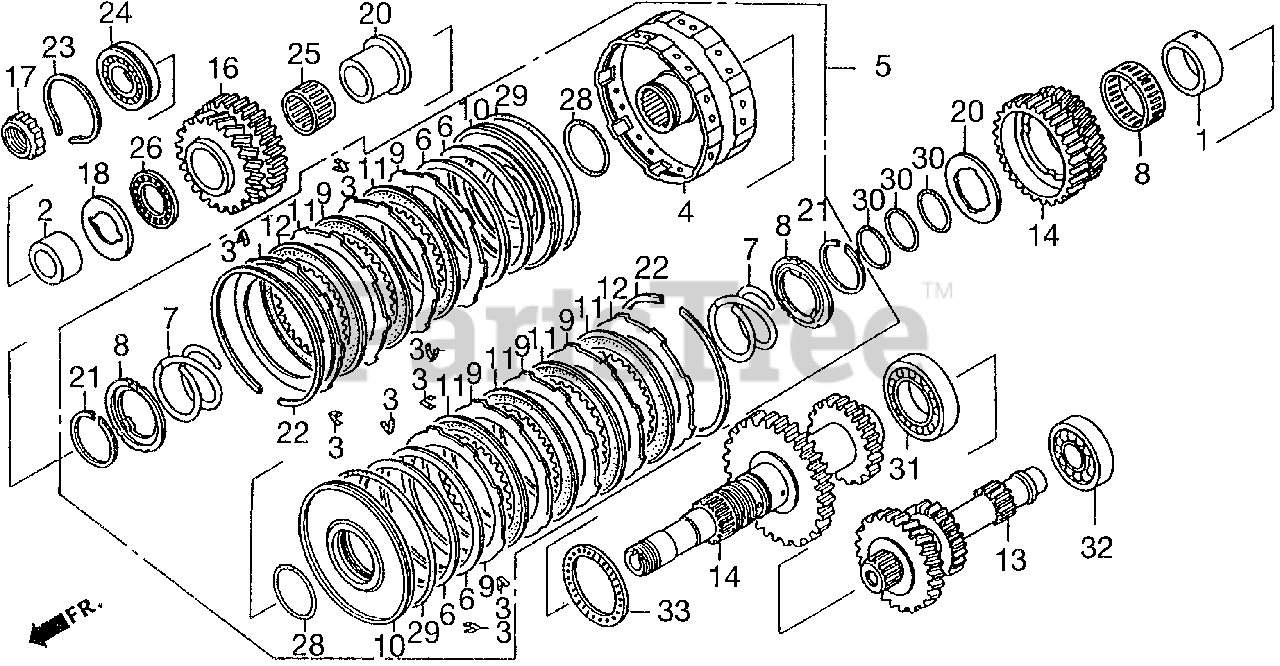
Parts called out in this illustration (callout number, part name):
1	COLLAR, DISTANCE
2	COLLAR (25MM) (NOT AVAILABLE)
3	SPRING, DISK SETTING
4	GUIDE, SECOND & THIRD CLUTCH
5	CLUTCH ASSY., SECOND & THIRD
6	SPRING, CLUTCH DISK
7	SPRING, CLUTCH RETURN
8	SEAT, CLUTCH SPRING
9	PLATE, CLUTCH (106)
10	PISTON, CLUTCH
11	DISK, CLUTCH
12	PLATE, CLUTCH END (2.3MM)
12	PLATE, CLUTCH END (2.6MM)
12	PLATE, CLUTCH END (2.9MM)
12	PLATE, CLUTCH END (3.2MM)
12	PLATE, CLUTCH END (3.5MM)
12	PLATE, CLUTCH END (2.15MM)
12	PLATE, CLUTCH END (2.45MM)
12	PLATE, CLUTCH END (2.75MM)
12	PLATE, CLUTCH END (3.05MM)
12	PLATE, CLUTCH END (3.35MM)
12	PLATE, CLUTCH END (3.65MM)
13	SHAFT, AUXILIARY DRIVE
14	COUNTERSHAFT
15	GEAR, SECOND DRIVEN (38T-28T)
16	GEAR, THIRD DRIVEN (38T-23T)
17	NUT, LOCK (25MM)
18	WASHER, THRUST (26X53X3)
19	WASHER, THRUST (36.5X56X3.50)
19	WASHER, THRUST (36.5X56X3.55)
19	WASHER, THRUST (36.5X56X3.60)
19	WASHER, THRUST (36.5X56X3.65)
19	WASHER, THRUST (36.5X56X3.70)
19	WASHER, THRUST (36.5X56X3.75)
19	WASHER, THRUST (36.5X56X3.80)
19	WASHER, THRUST (36.5X56X3.85)
20	COLLAR, THIRD DRIVEN
21	CIRCLIP (OUTER) (40MM) (F.C.C.)
22	RING, SNAP (114X1.8)
23	RING, SNAP (52MM)
24	BEARING, SPECIAL BALL (6205) (NOT AVAILABLE)
25	BEARING, NEEDLE (31X36X18.5)
26	BEARING, THRUST NEEDLE (31X47X2)
27	BEARING, NEEDLE (43X48X17)
28	O-RING (39.8X2.2) (ARAI)
29	O-RING (100X2.2) (NOK)
30	O-RING (31.2X1.9) (ARAI)
31	BEARING, RADIAL BALL (6007)
32	BEARING, RADIAL BALL (6204U)
33	BEARING, THRUST (WU)
